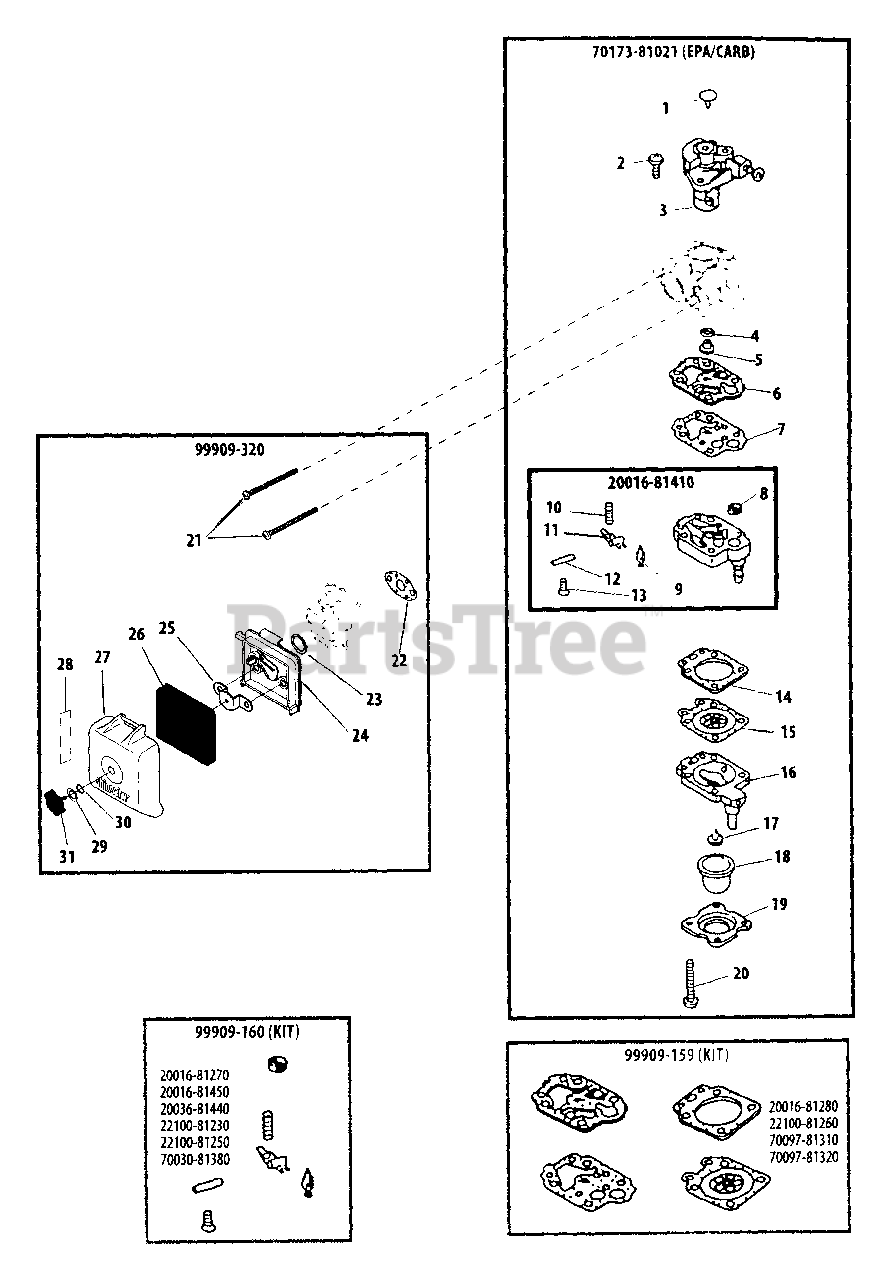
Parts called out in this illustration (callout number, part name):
1	PLUG
2	SCREW, THROTTLE COLLAR
3	THROTTLE VALVE ASSY
4	O-RING
5	MAIN JET - #38
6	GASKET, PUMP
7	DIAPHRAGM, PUMP
8	SCREEN, FUEL INLET
9	VALVE, INLET NEEDLE
10	SPRING, METERING LEVER
11	LEVER, METERING
12	PIN, METERING LEVER
13	SCREW
14	GASKET, METERING DIAPHRAGM
15	DIAPHRAGM, METERING
16	BODY ASSY, PURGE
17	VALVE, CHECK
18	BULB, PURGE
19	RETAINER, PURGE BULB
20	SCREW
21	SCREW - 5×67
22	GASKET, CARBURETOR
23	O-RING 15
24	CASE, AIR FILTER
25	BRACKET
26	FILTER, AIR
27	COVER, AIR FILTER
28	LABEL, CHOKE
29	WASHER, CONE M6
30	O-RING
31	THUMBSCREW
20016-81410	BODY ASSY, PUMP
70173-81021	CARBURETOR
99909-159	GASKET / DIAPHRAGM KIT
99909-160	VALVE KIT, INLET NEEDLE
99909-320	AIR FILTER ASSY
